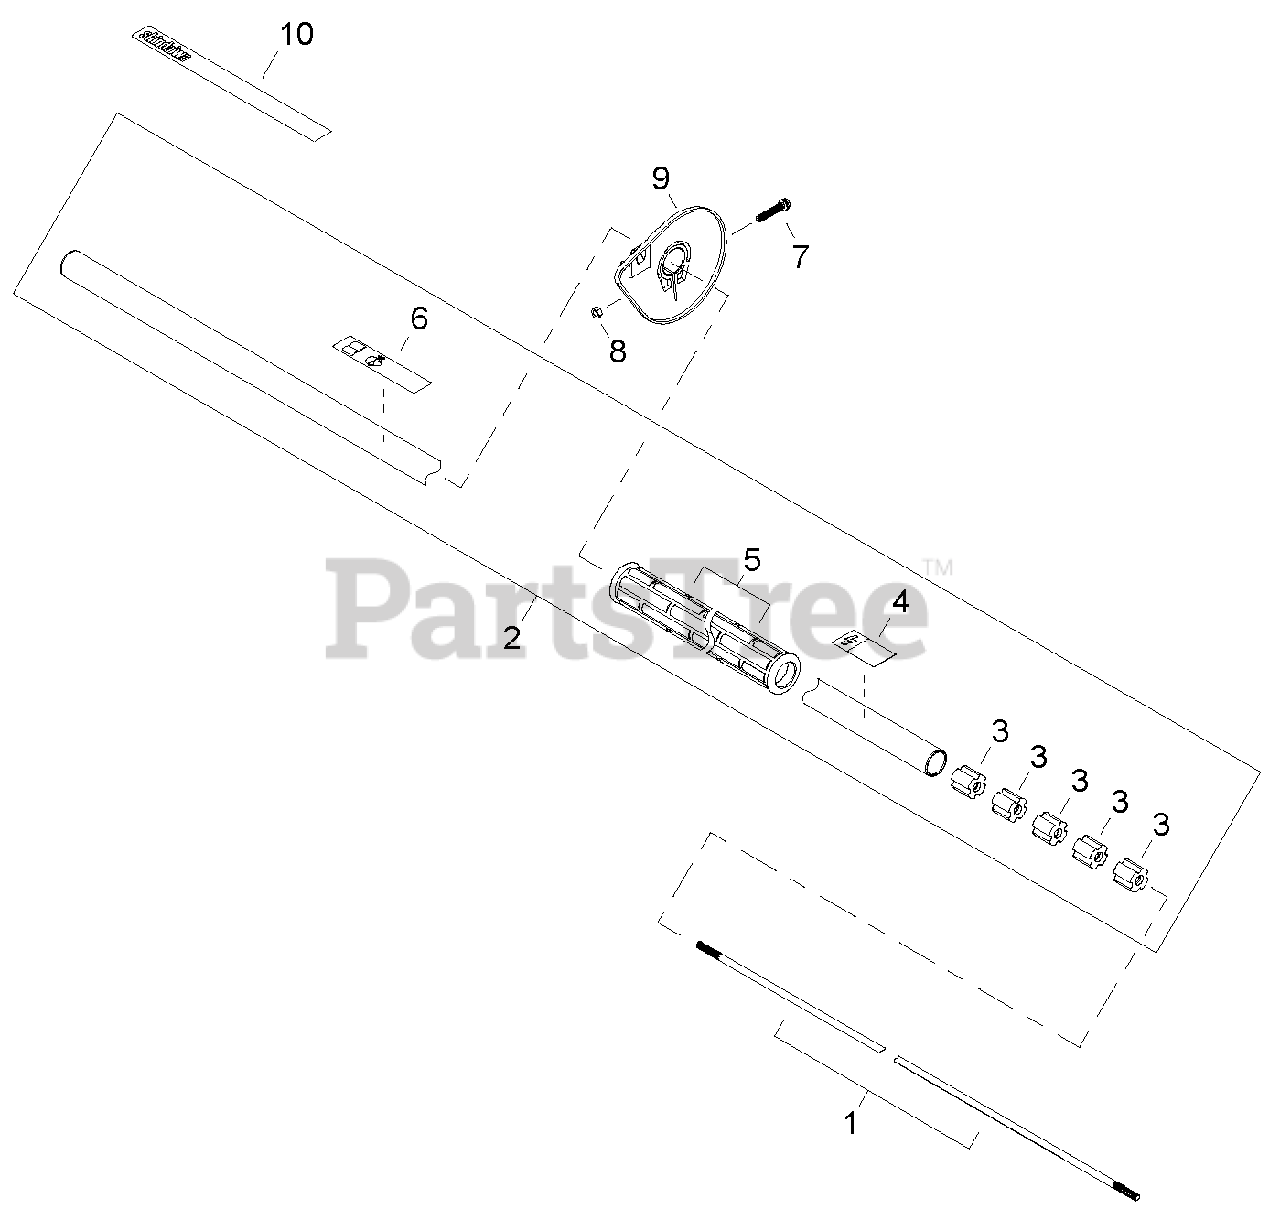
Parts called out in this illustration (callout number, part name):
2	MAIN PIPE ASSY
3	BUSHING
4	LABEL - HIGH VOLTAGE
5	GRIP - FRONT
6	LABEL - CAUTION
7	SCREW - 5X30
8	NUT - 5
9	GUARD, HAND
9-1	PIPE, MAIN
10	LABEL - SHINDAIWA PROFESSIONAL
